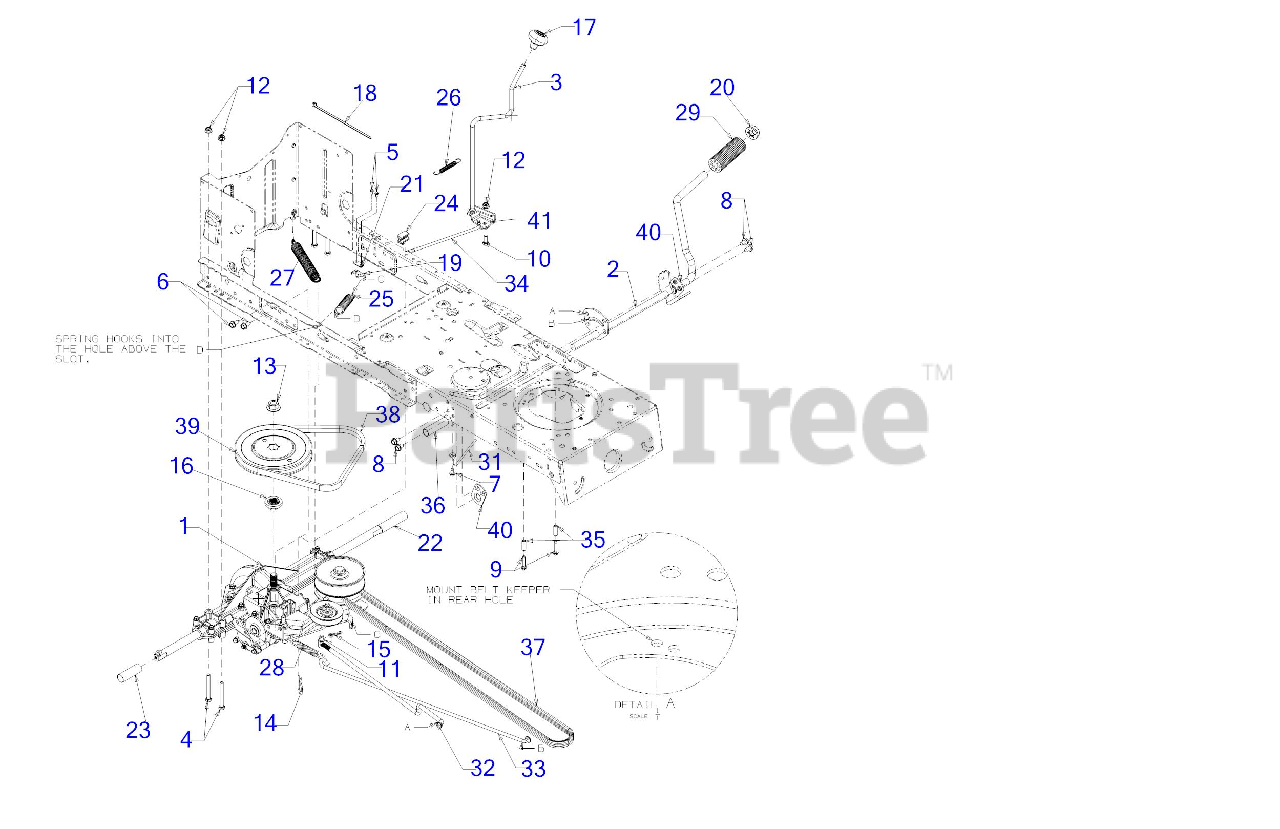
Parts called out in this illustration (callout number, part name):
1	TRANSMISSION ASSEMBLY
3	SHIFT LEVER ASSEMBLY
4	HEX SCREW 5/16-18 x 2.75
5	HEX SCREW WASHER HD #8-18 x 0.500
6	SCREW 5/16-18 x .750
7	SCREW 1/4-20 X.500
8	SCREW 5/16-18 x .625
9	SCREW 1/4-20 x 1.25
10	SCREW 5/16-18 x .75 GR5
11	FERRULE 3/8-24 x .375
12	FLANGE LOCK NUT 5/16-18
13	FLANGE NUT W/HUB
14	COTTER PIN
15	BOW TIE COTTER PIN 1/4-5/16
16	PULLEY HUB
17	SHIFT KNOB
18	7" CABLE TIE
19	SAFTEY SPRING SWITCH
20	PUSH CAP
21	INSULATOR PLATE
22	SLEEVE
23	SLEEVE
24	SHIFT ROD BEARING
25	EXTENSION SPRING
26	EXTENSION SPRING .38 OD x 3.25 LG
27	EXTENSION SPRING .94 x 6.75
28	EXTENSION SPRING
29	FOOT PAD 4.0" LG
31	BELT KEEPER ROD
32	VARIABLE SPEED ROD
33	BRAKE ROD
34	SHIFT ROD
35	SPACER
36	SPACER-5/8 ID x 2.
37	V-BELT 70.90
37	Genuine Factory Parts TRANSMISSION BELT
38	V-BELT 5L x 35.25
38	Genuine Factory Parts TRANSMISSION BELT
39	V- PULLEY W/HUB
41	SHIFT ADJUSTMENT BRACKET
